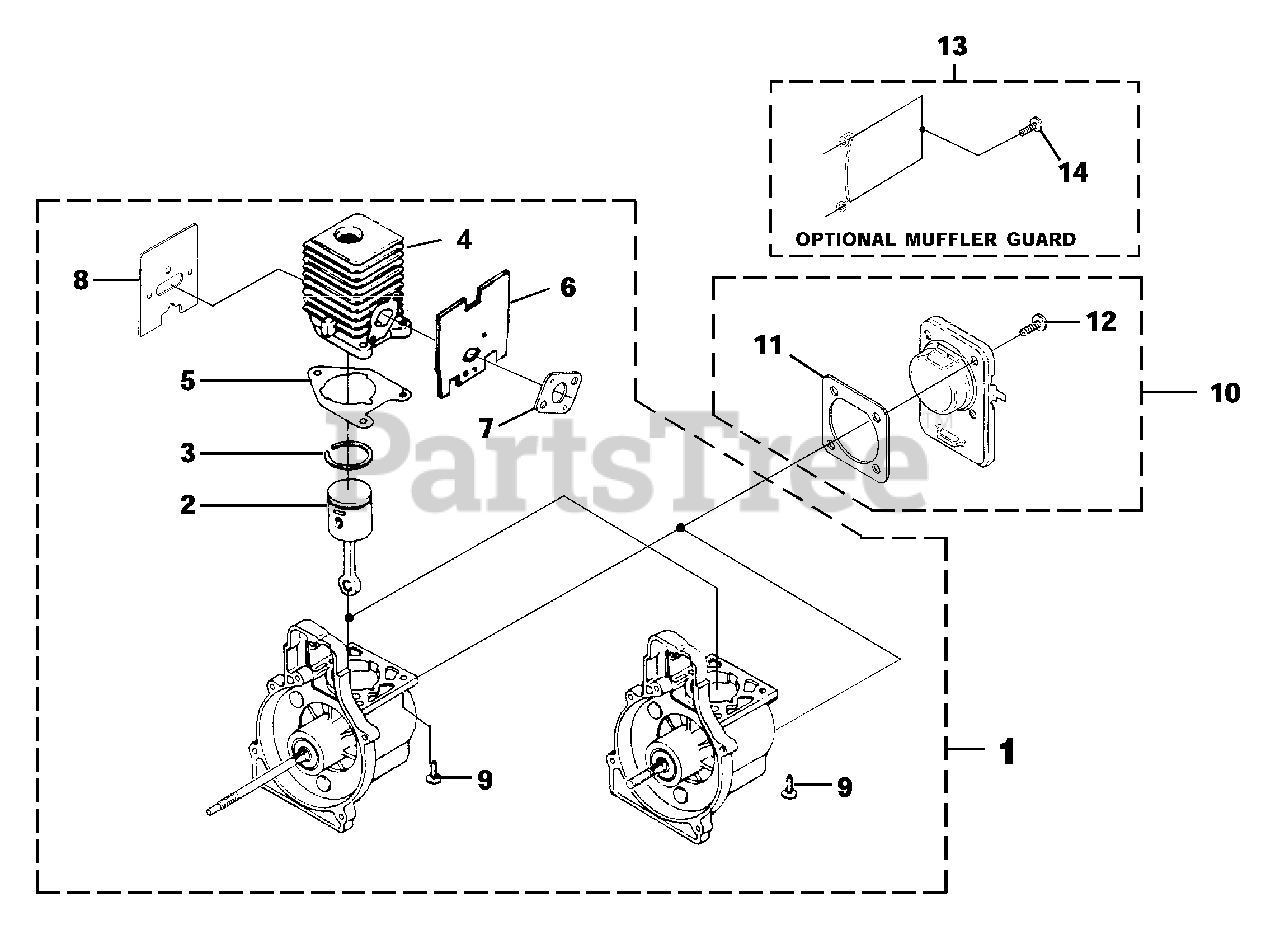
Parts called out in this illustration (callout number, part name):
1	SHORT BLOCK (Non-Clutch)
2	PISTON & ROD ASSY.
3	RING-Piston
4	CYLINDER ASSY.
5	GASKET-Cylinder
6	GASKET-Heat Dam
7	GASKET-Carburetor
8	GASKET-Muffler
9	SCREW-Sems (12-24 X 3/4")
10	CRANKCASE COVER ASSEMBLY
11	GASKET-Crankcase Cover
12	SCREW-Sems (10-24 X 1/2")
13	MUFFLER GUARD
14	SCREW-Plastite (10-14 X 1/2")
